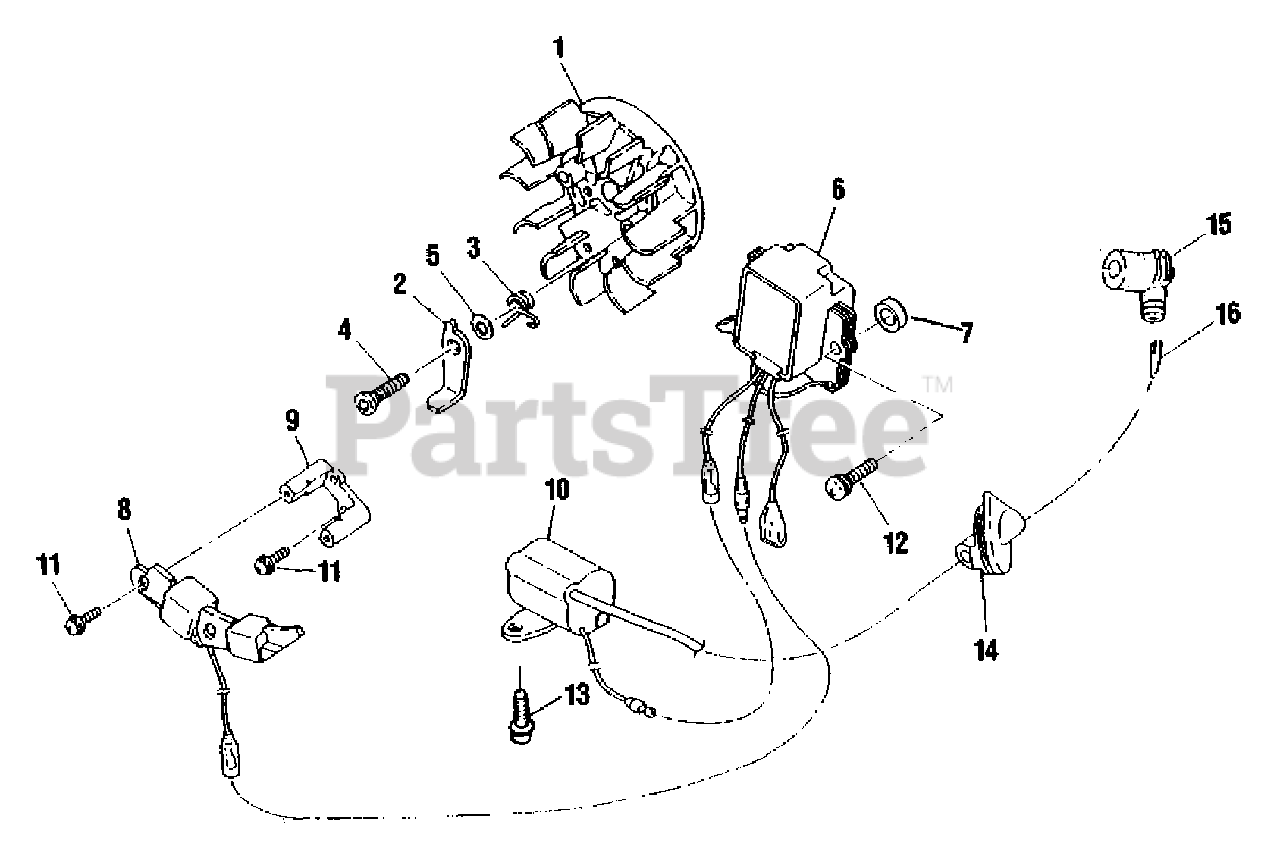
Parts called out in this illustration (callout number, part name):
1	ROTOR
2	PAWL, STARTER
3	SPRING, RETURN
4	SCREW
5	WASHER - 6
6	EXCITER, COIL
7	INSULATOR
8	PULSER COIL
9	PULSER BRACKET
10	COIL, IGNITION
11	SCREW - 4X14
12	SCREW - 5X20
13	SCREW - 4X10
15	CAP, SPARK PLUG
16	TERMINAL, SPARK PLUG CAP
